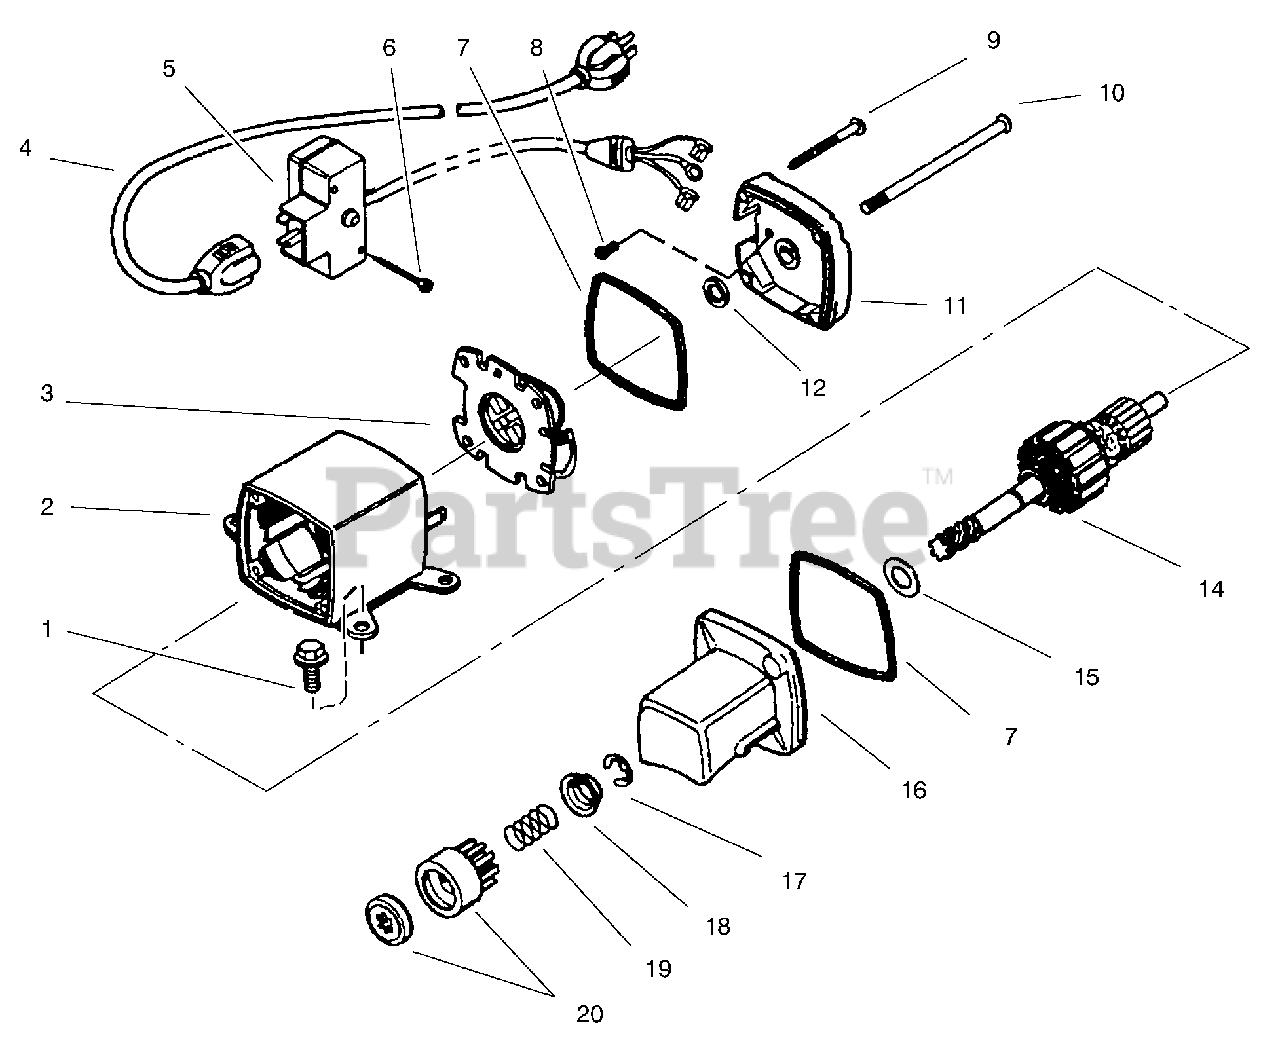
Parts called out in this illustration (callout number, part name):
1	Screw-Torx
2	Housing Asm
3	Brush Card ASM
4	Cord-Extension
5	Switch Box ASM
8	Ground Screw
9	Ground Screw
10	Bolt-Case
11	Cap-Commutator End Asm (Incl. Ref. #7)
12	Thrust Washer
14	Armature
15	Thrust Washer
16	Cap-Drive End (Incl. Ref.# 7)
17	Ring Retainer
18	Retainer-Spring
19	Spring-Anti Drift
20	Nut & Gear
